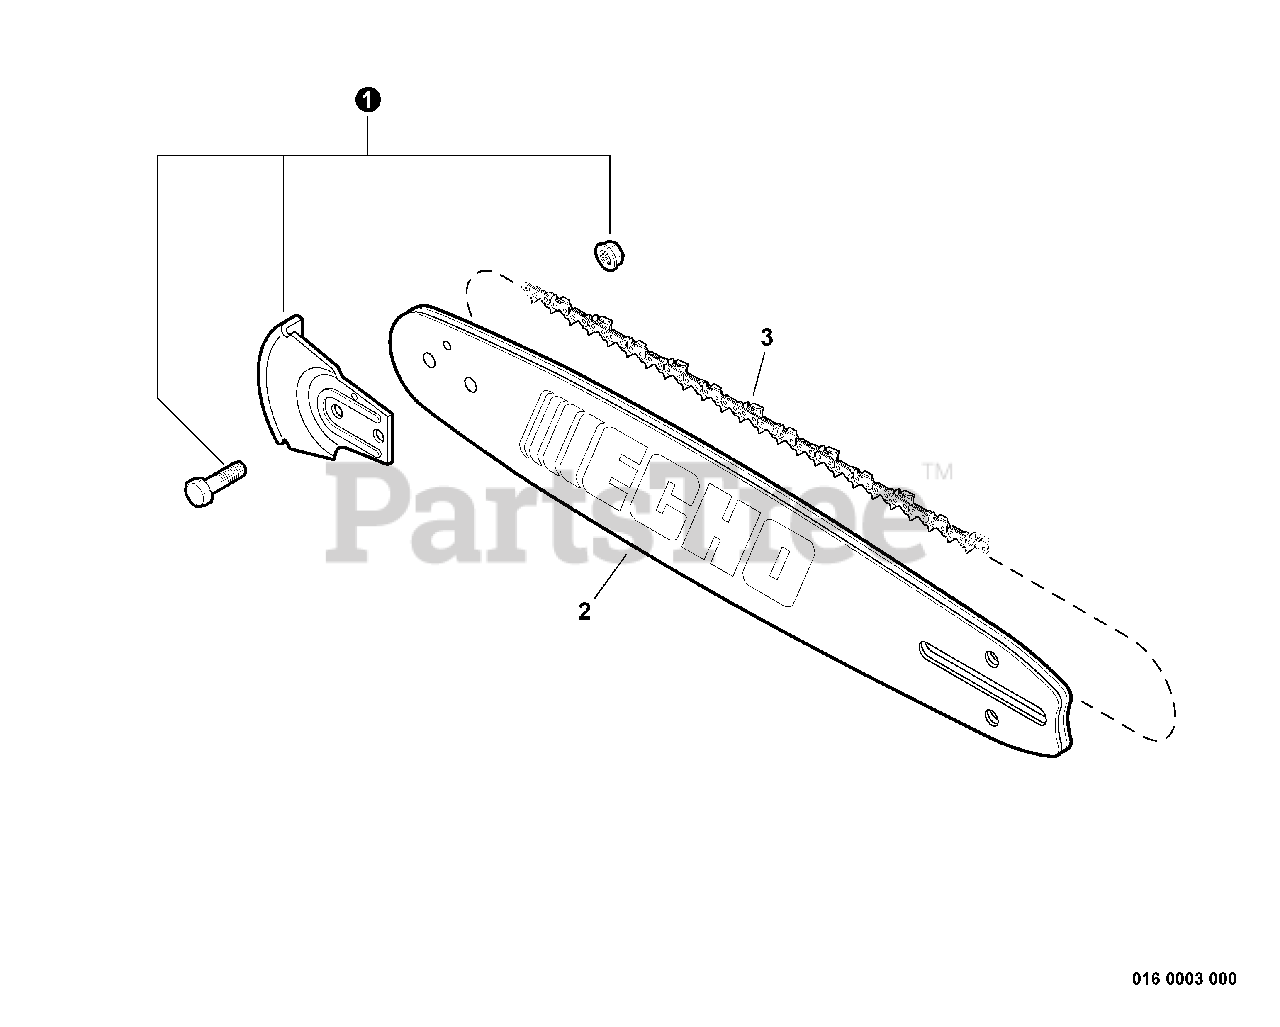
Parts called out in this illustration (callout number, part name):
1	KICK GUARD KIT
2	GUIDE BAR, 12" DOUBLE-GUARD
2	GUIDE BAR, 14" DOUBLE-GUARD
2	GUIDE BAR, 16" DOUBLE-GUARD
2	GUIDE BAR, 12"
2	GUIDE BAR, 14"
2	GUIDE BAR, 16"
3	SAWING CHAIN - 12" -- XTRAGUARD
3	SAW CHAIN 14" XTRAGUARD
3	SAW CHAIN 16"
